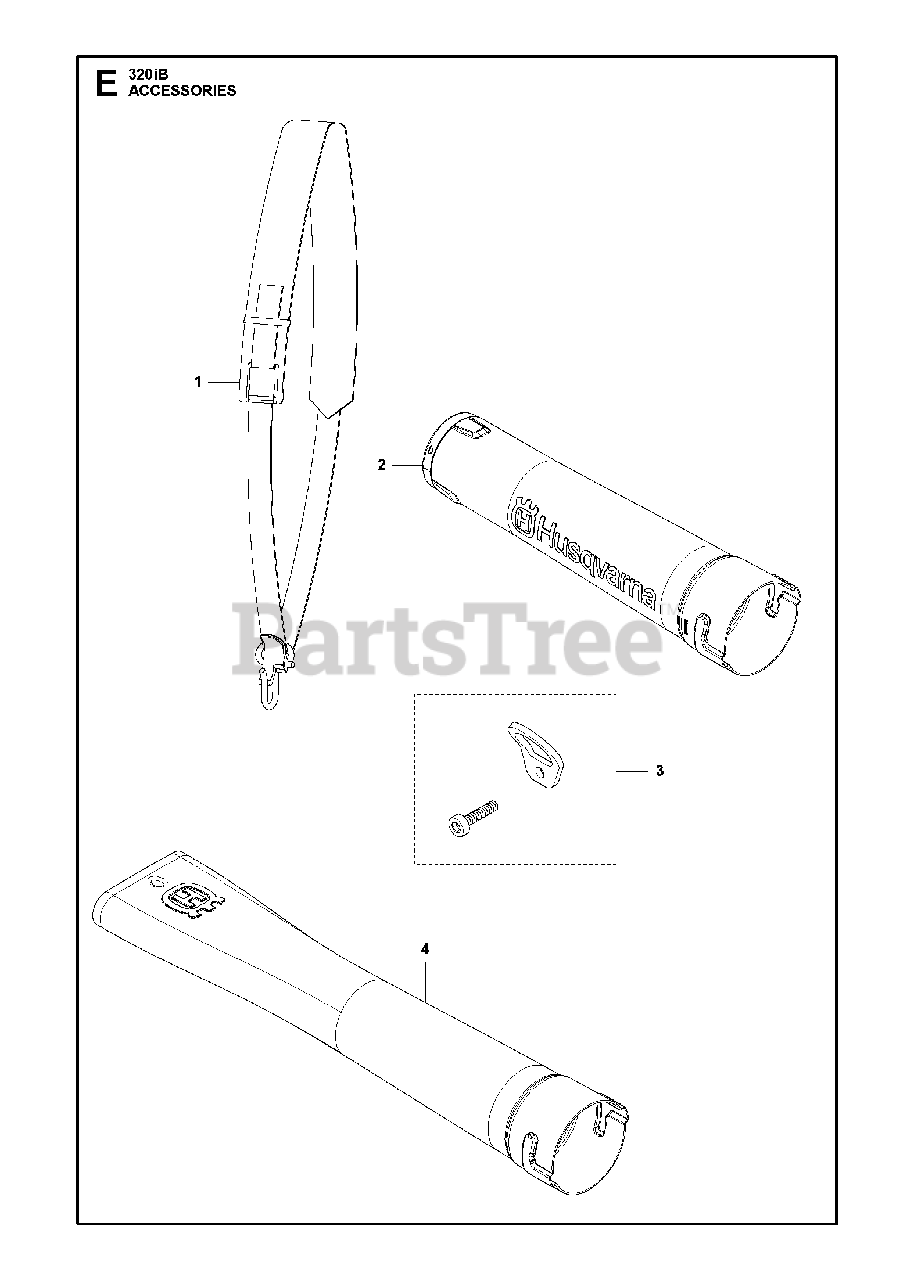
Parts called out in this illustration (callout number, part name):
1	STRAP
2	TUBE ASSY NOZZLE 536LIBX
3	KIT EYELET
4	BLOWER NOZZLE FOR 320
